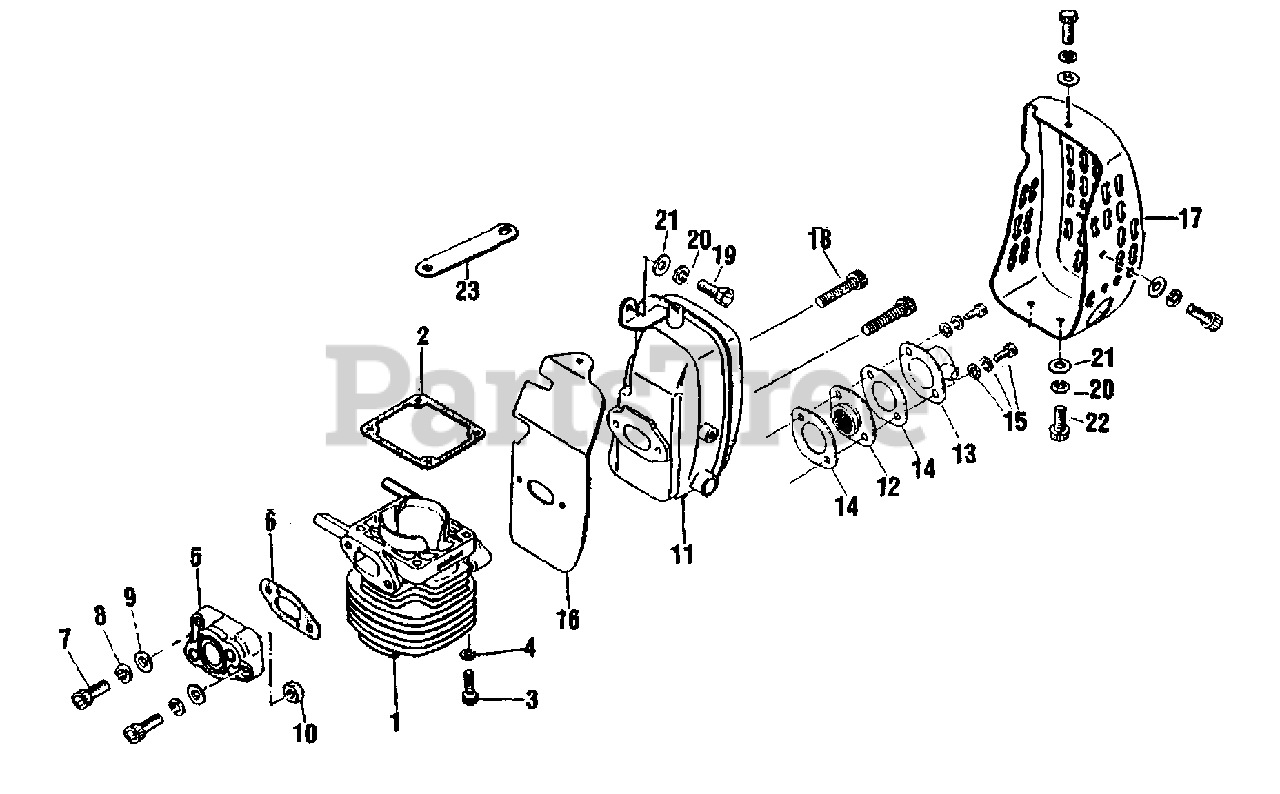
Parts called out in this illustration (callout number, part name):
1	CYLINDER
2	GASKET, CYLINDER
3	BOLT 5×25
4	WASHER, SPRING 5
5	INSULATOR
6	GASKET, INTAKE
7	BOLT 5×25
8	WASHER, SPRING 5
9	WASHER, FLAT 5.5×10×0.8
10	NUT M5
11	MUFFLER
12	SCREEN, SPARK ARRESTER
13	GUIDE, EXHAUST
14	GASKET, EXHAUST
15	SCREW
16	HEAT SHIELD, EXHAUST
17	GUARD, MUFFLER
18	BOLT 6×25
19	BOLT 5×12
20	WASHER, SPRING 5
21	WASHER
22	BOLT M5×10
23	STAY, MUFFLER
